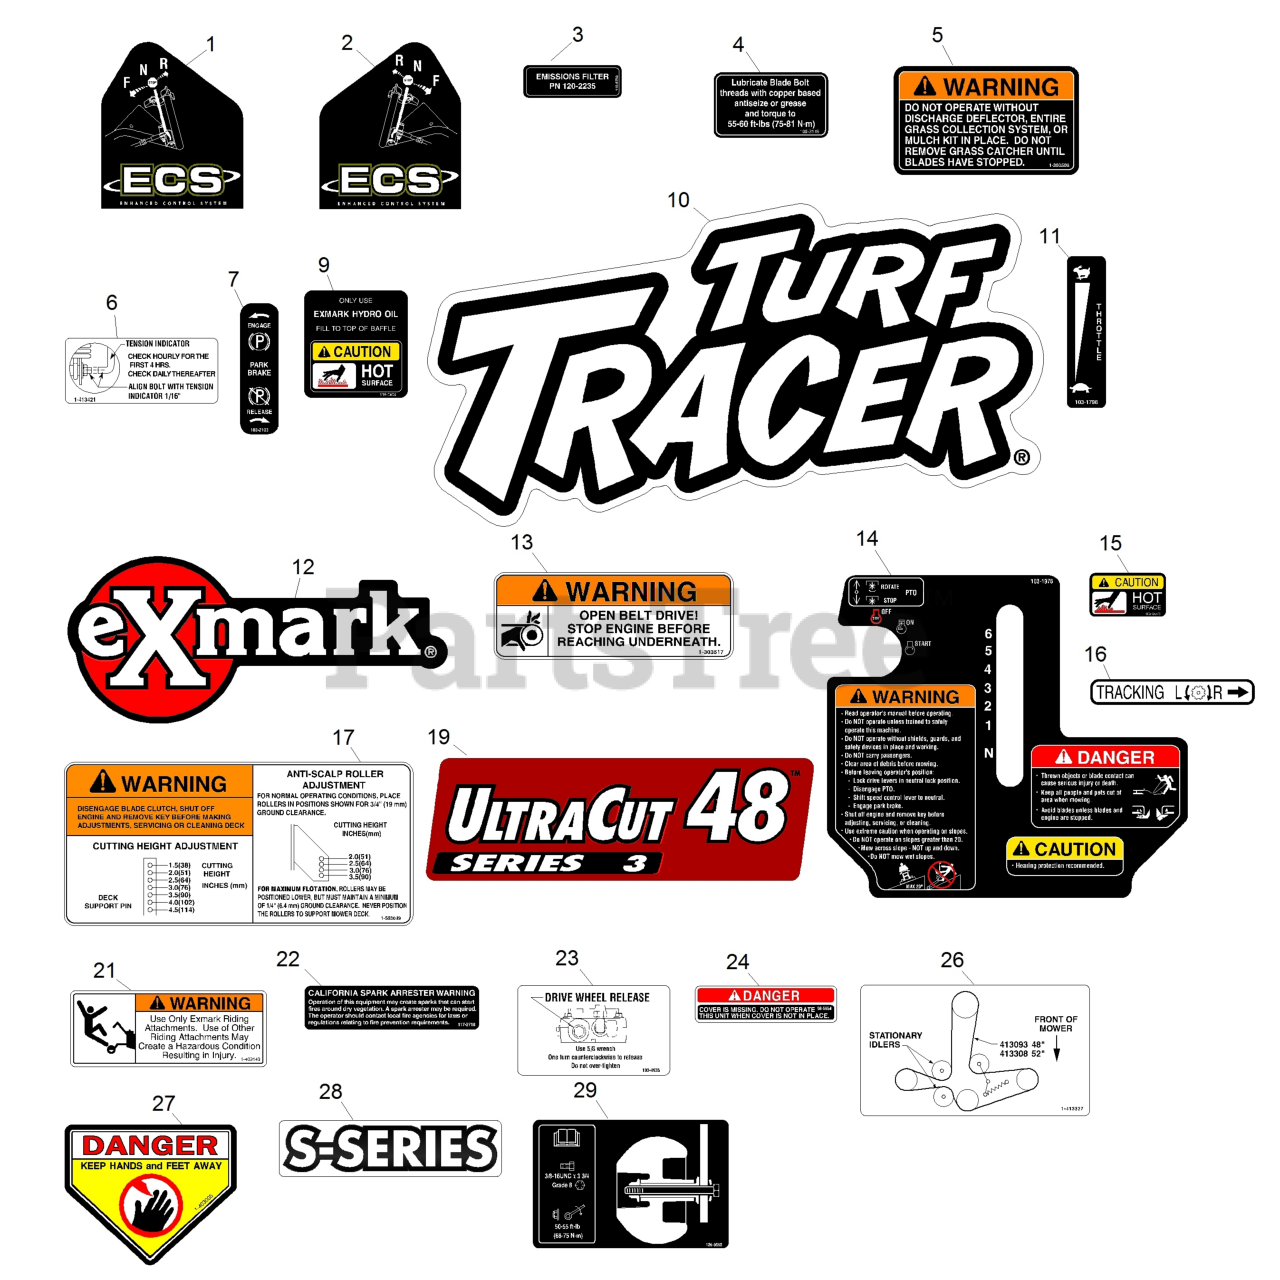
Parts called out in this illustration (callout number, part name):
1	DECAL,LH ECS INSTRUCTION
2	DECAL,RH ECS INSTRUCTION
3	DECAL-FILTER, EMISSIONS
4	DECAL,BOLT TORQUE
5	DECAL-WARNING, DISCHARGE
6	DECAL,INDICATOR
7	DECAL-BRAKE, PARK
9	DECAL-HYDRAULIC TANK
10	DECAL,TTH MODEL
11	DECAL,THROTTLE ONLY
12	DECAL,EXMARK LOGO
13	DECAL,BELT DRIVE
14	DECAL,CONSOLE
15	DECAL-CAUTION
16	DECAL,TRACKING ADJUST
17	DECAL,ANTI SCALP
19	DECAL-ULTRACUT 48 SERIES
21	DECAL,SULKY WARNING
22	DECAL-ARRESTER, SPARK
23	DECAL,DRIVE RELEASE
24	DECAL-COVER, MISSING
26	DECAL,BELT ROUTING
27	DECAL-DANGER
28	DECAL-S-SERIES
29	DECAL-ROLLER MOUNTING
